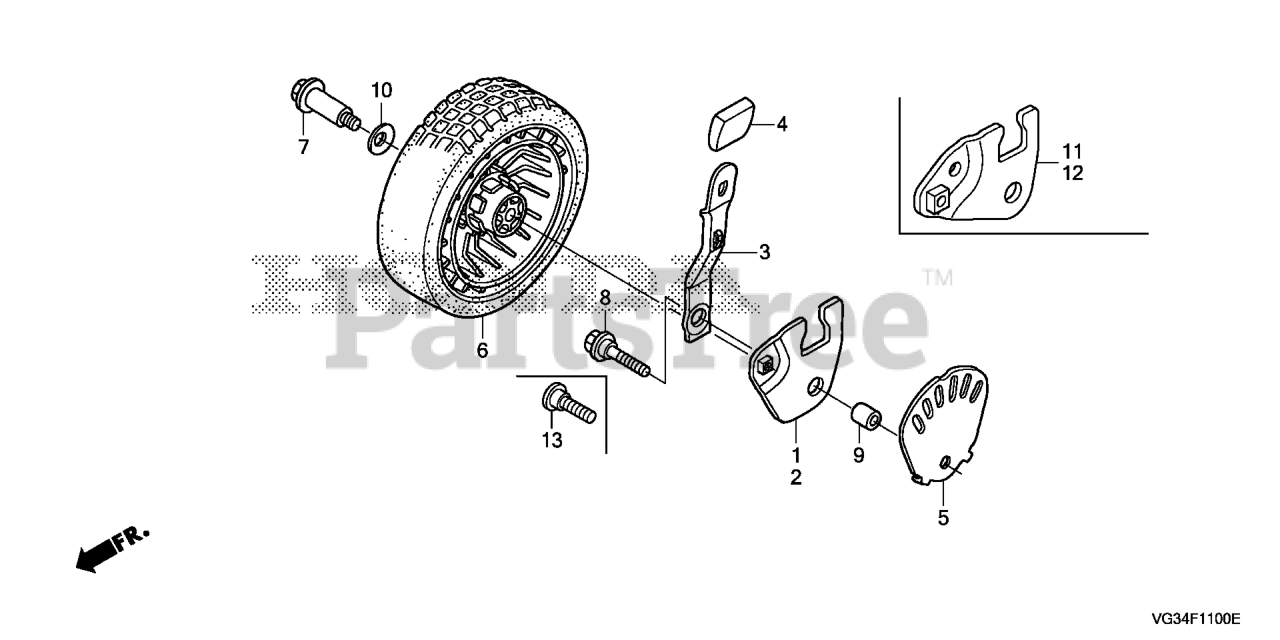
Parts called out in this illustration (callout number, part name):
3	PLATE, FR. ADJUSTER
4	GRIP, ADJUSTER *NH164* (GRIP GRAY)
5	PANEL, FR. ADJUSTER
6	WHEEL, FR. *NH462R* (VINTAGE GRAY SOLID)
7	BOLT, FR. WHEEL SHAFT
9	COLLAR, FR. ADJUSTING
10	WASHER, WHEEL
11	ARM, R. FR. ADJUSTER
12	ARM, L. FR. ADJUSTING
13	BOLT, ADJUSTER ARM
